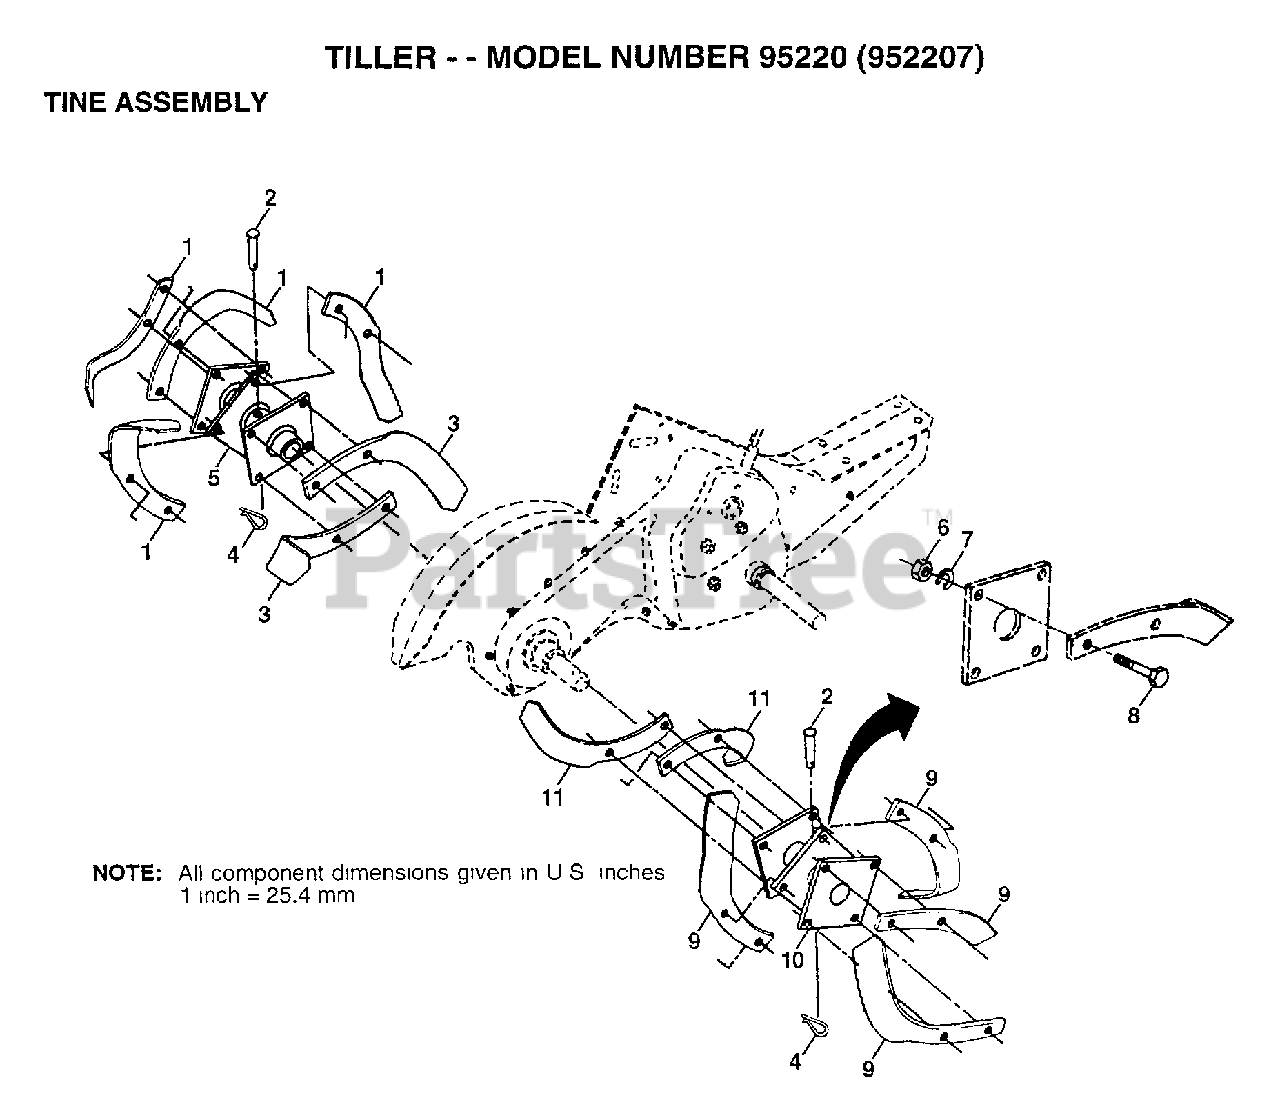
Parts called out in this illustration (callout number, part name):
1	Tine, Outer, L.H.
2	PIN.CLEVIS.SHEAR
3	TINE.LH.12"
4	RETAINER.SPRING
5	HUB&PLATE ASM LH
7	LOCKWASHER
8	BOLT
10	HUB&PLATE ASM RH
11	TINE.RH.12"
